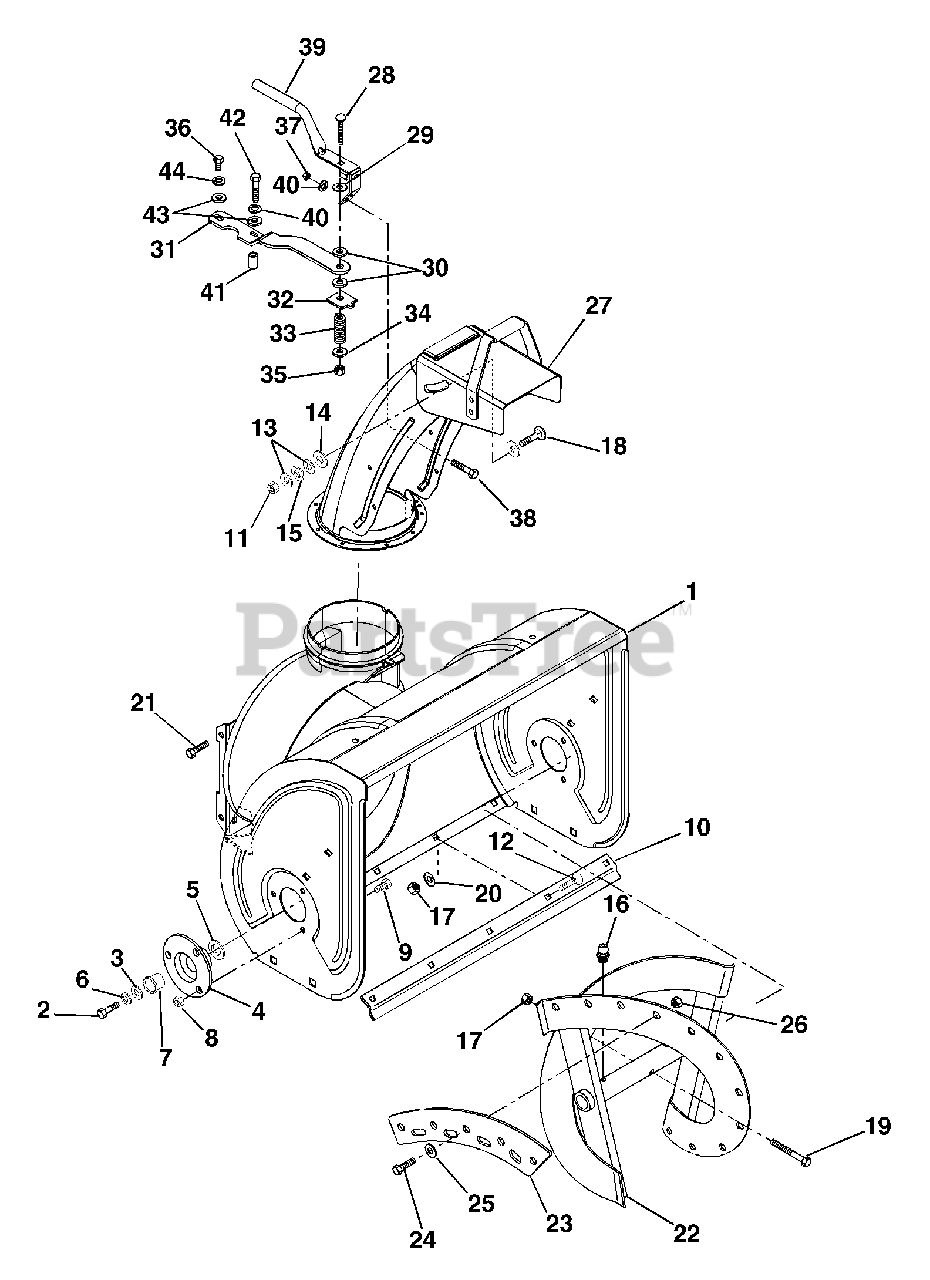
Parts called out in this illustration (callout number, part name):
1	HOUSING, BLOWER - 20"
2	@BLT-HEX .31-18X.50 GR5 YWZC
3	WSHR-FL-STL .347X1.254X.048YWZ
4	BEARING FLANGE ASSEMBLY
5	@WSHR-FL-STL.812X1.50X.135YWZC
6	@WSHR-LK .31X.078 REG YWZC
7	BSHG-FLG .750X1.000X.625X1.250
8	@NUT-SPNLK-FLG .25-20 YWZC
9	BLT-SERNK SL .25-20X.50 YWZC
10	SCRAPER BLADE, 20"
11	@NUT-LK-CTR .31-18 YWZC
12	@BLT-RDHDSQNK .25-20X.50 G5YZ
13	@WSHR-FL-STL.344X.688X.065YWZC
14	WSHR-PLASTIC .390X.875X.062
15	WAVE WASHER .390X.655X.110
16	ZERK,FITTING .25X.125 DRIVE IN
17	@NUT-LK-CTR .25-20 YWZC
18	@BLT-RHDSSQNK .31-18X.75 G5YZ
19	SHEAR BOLT WITH NUT
20	@WSHR-FL-STL.281X.62X.065 YWZC
21	@SCR-TAP .38-16X.75 HWH TR YWZ
22	RAKE, RIGHT-20(.75ID X 10.5OD)
23	RAKE EDGE W/HARDWARE
24	BLT-HEX 10-24X.63 PL
25	@WSHR-FL-STL .188X.438X.049 YZ
26	NUT-LK TOP 10-24 PL
27	CHUTE, DISCHARGE W/CAP
28	@BLT-RDHDSQNK .38-16X2.25 G5YZ
29	@WSHR-FL-STL.563X1.38X.109YWZC
30	FRICTION WASHER
31	BRACE, CHUTE CONTROL
32	FRICTION PLATE
33	SG-COMP .187X.56X1.62
34	@WSHR-FL-STL.406X.812X.065 YWZ
35	@NUT-LK-CTR .38-16 YWZC
36	@BLT-HEX .31-18X.75 GR5 YWZC
37	@NUT-HEX .25-20 YWZC
38	@BLT-HEX .25-20X.50 GR5 YWZC
39	HANDLE, COATED CHUTE
40	WSHR-LK .250X.077 HVY YWZC
41	SPACER .280X.625X.640
42	@BLT-HEX .25-20X1.50 GR5 YWZC
43	WSHR-FL-STL .328X.875X.062YWZC
44	WSHR-LK .312X.097 HVY YWZC
